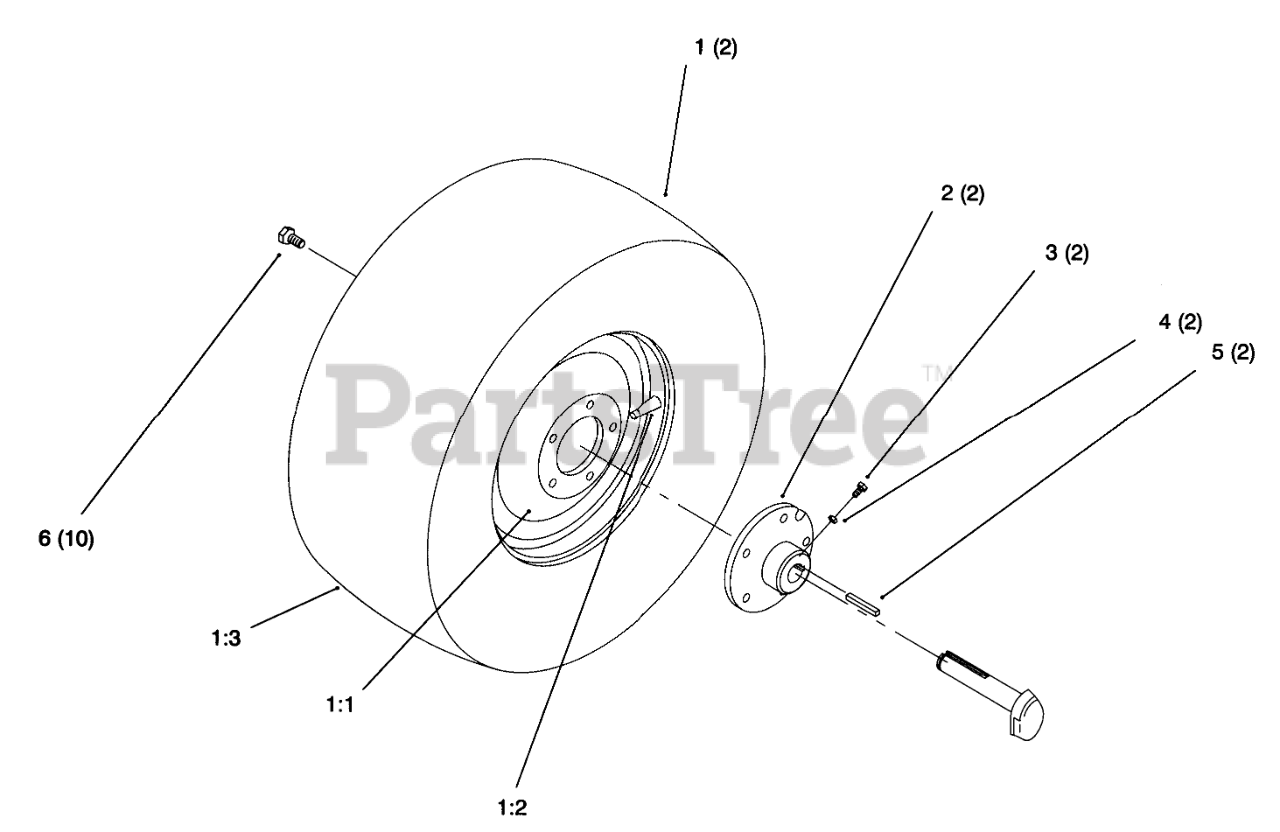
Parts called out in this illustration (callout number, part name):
1:1	WHEEL
1:2	VALVE
1:3	Tire (Only On: 72042, 72043, 72062, 72063)
1:3	Tire (Only On: 72103)
2	HUB-WHEEL
3	SCREW-SET, SQH
4	NUT-JAM
5	KEY-SQUARE
6	BOLT-LUG
